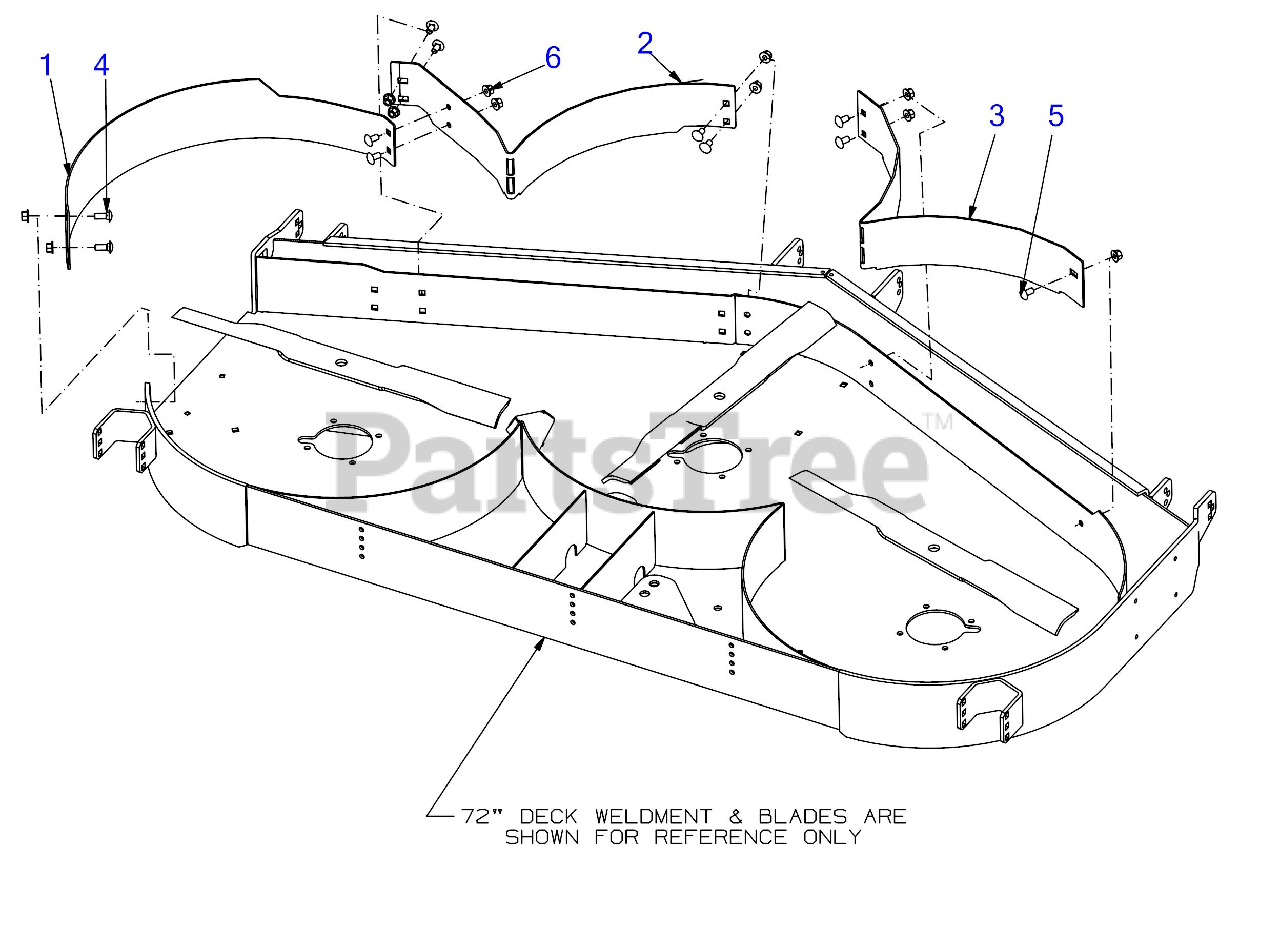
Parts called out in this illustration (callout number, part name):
4	CARRIAGE BOLT 3/8-16 x 1.00 GR5
5	CARRIAGE BOLT 3/8-16 x .75
6	NUT-CTRLCK FLG HEX
